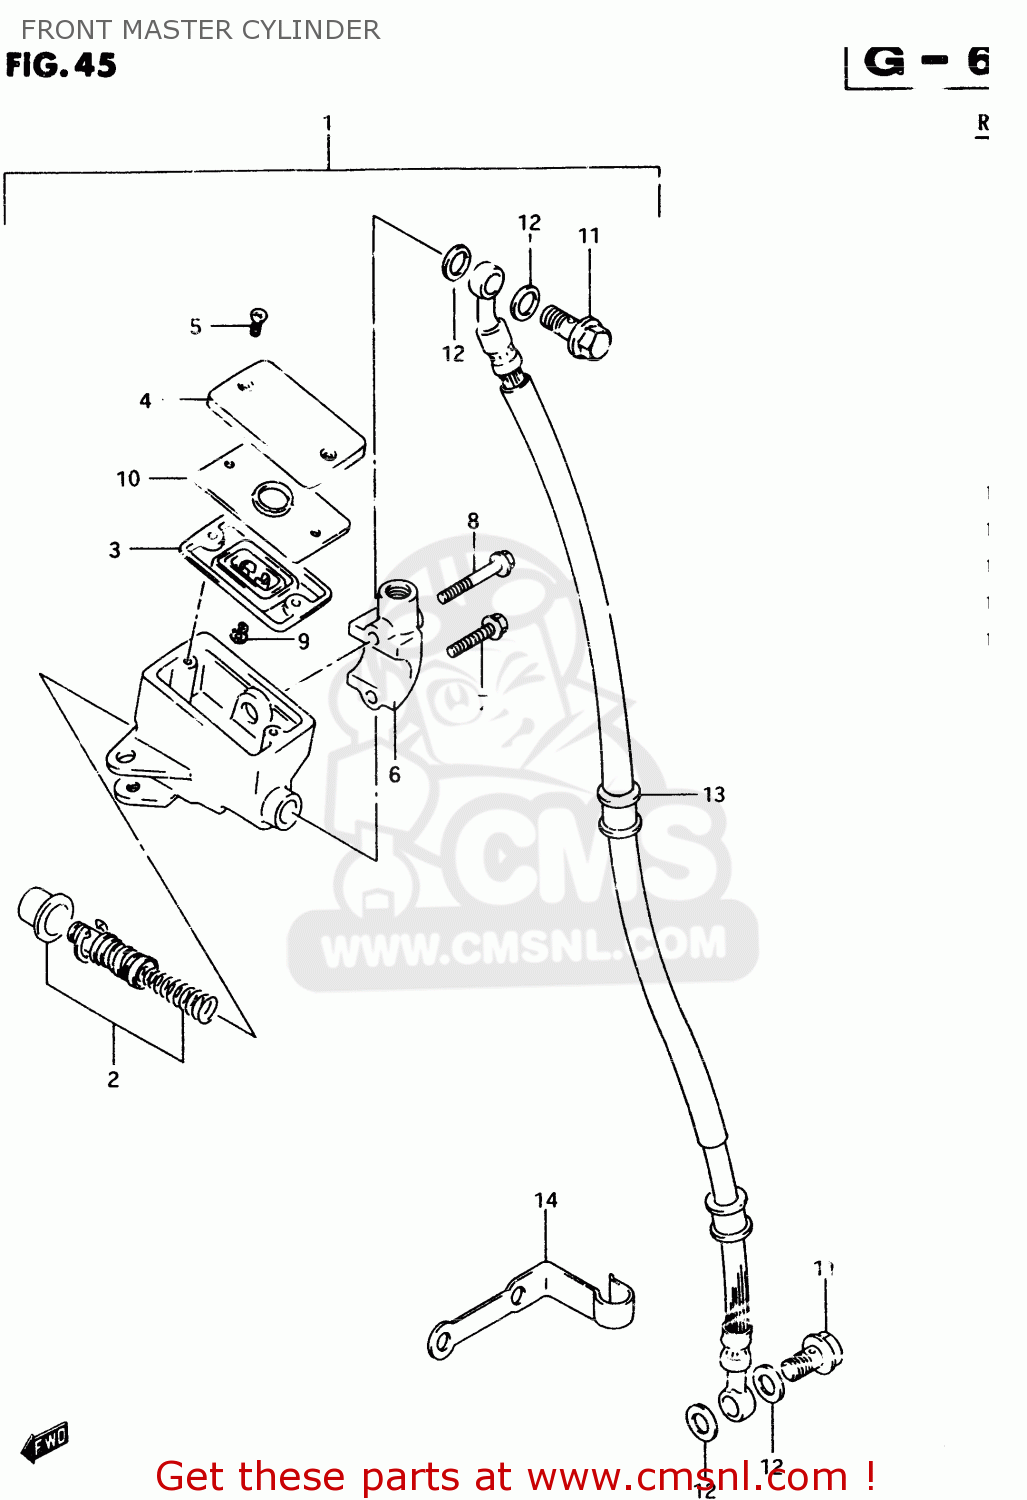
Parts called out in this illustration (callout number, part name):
1	CYLINDER ASSY,FR MASTER
2	PISTON/CUP SET
3	4
4	CAP
5	SCREW
6	HOLDER
7	BOLT(6X25)
8	BOLT(6X38)
9	PROTECTOR
10	PLATE,DIAPHRAGM
11	BOLT UNION
12	WASHER(10X15X1.5)
13	HOSE,FR BRAKE
14	CLAMP,BRAKE HOSE
